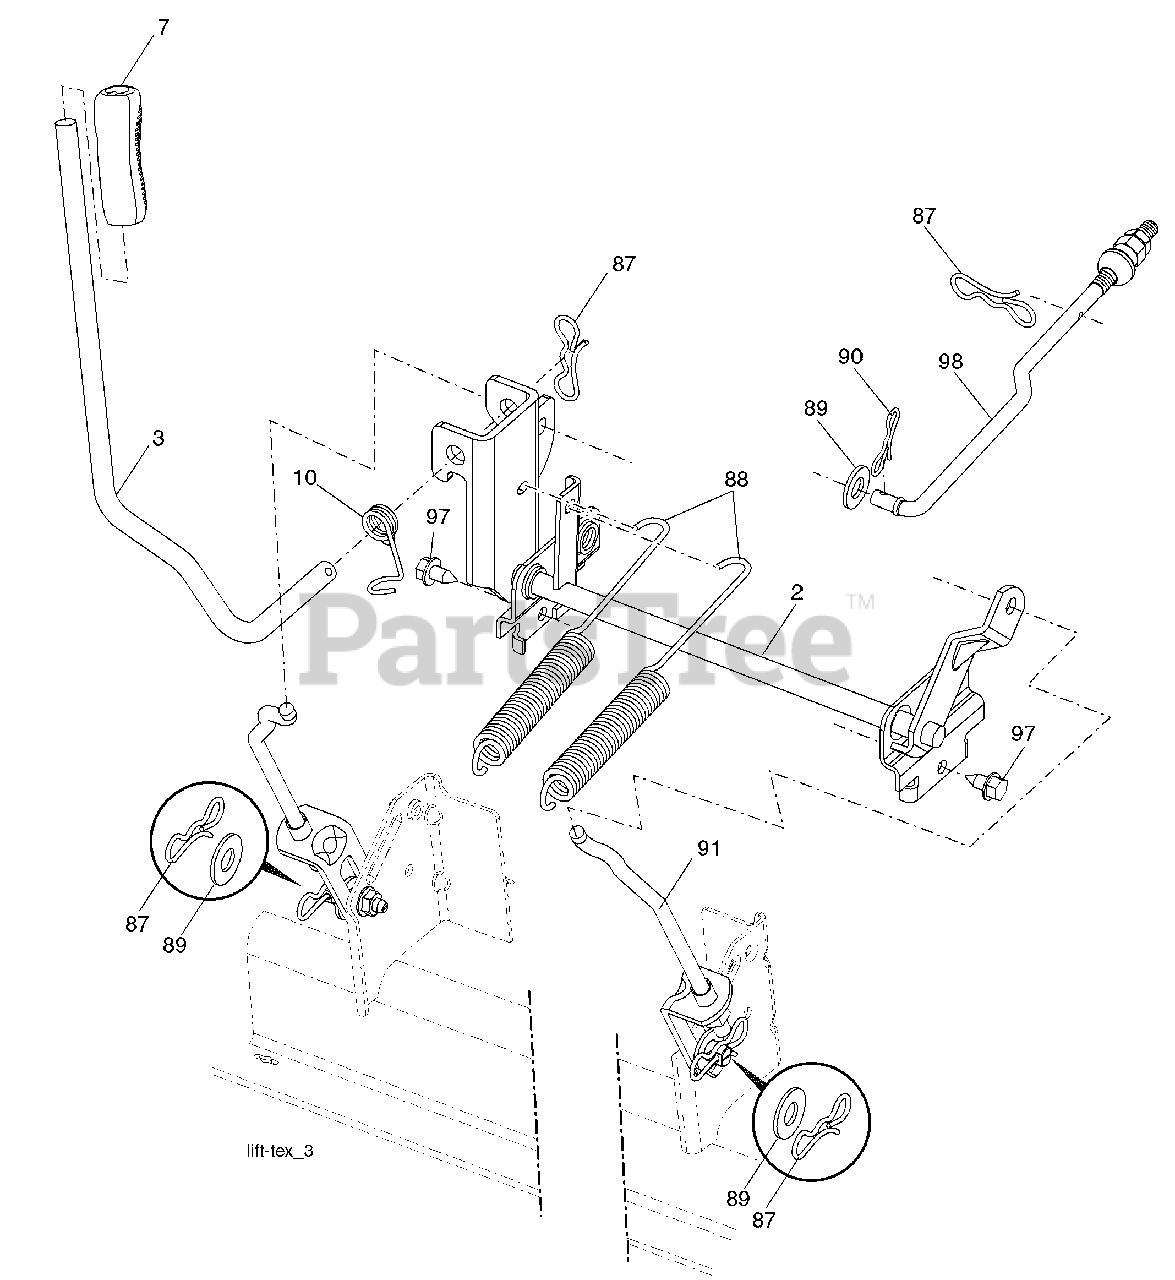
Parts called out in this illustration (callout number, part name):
2	Shaft Asm.,Lift
3	Lever Asm.,Lift Rh
7	Grip, Lever
10	Spring Torsion
87	Pin Cotter 7/16 Bow Tie Lock
88	Spring Lift Assist
89	Washer Clear Zinc
90	Pin Cotter 5/16 Bow Tie Lock
91	Link Lift Susp Mower Rear
97	Screw 3/8-16x.75 Smgml Tap/R.Z
98	Link Lift Susp. Front Mower
